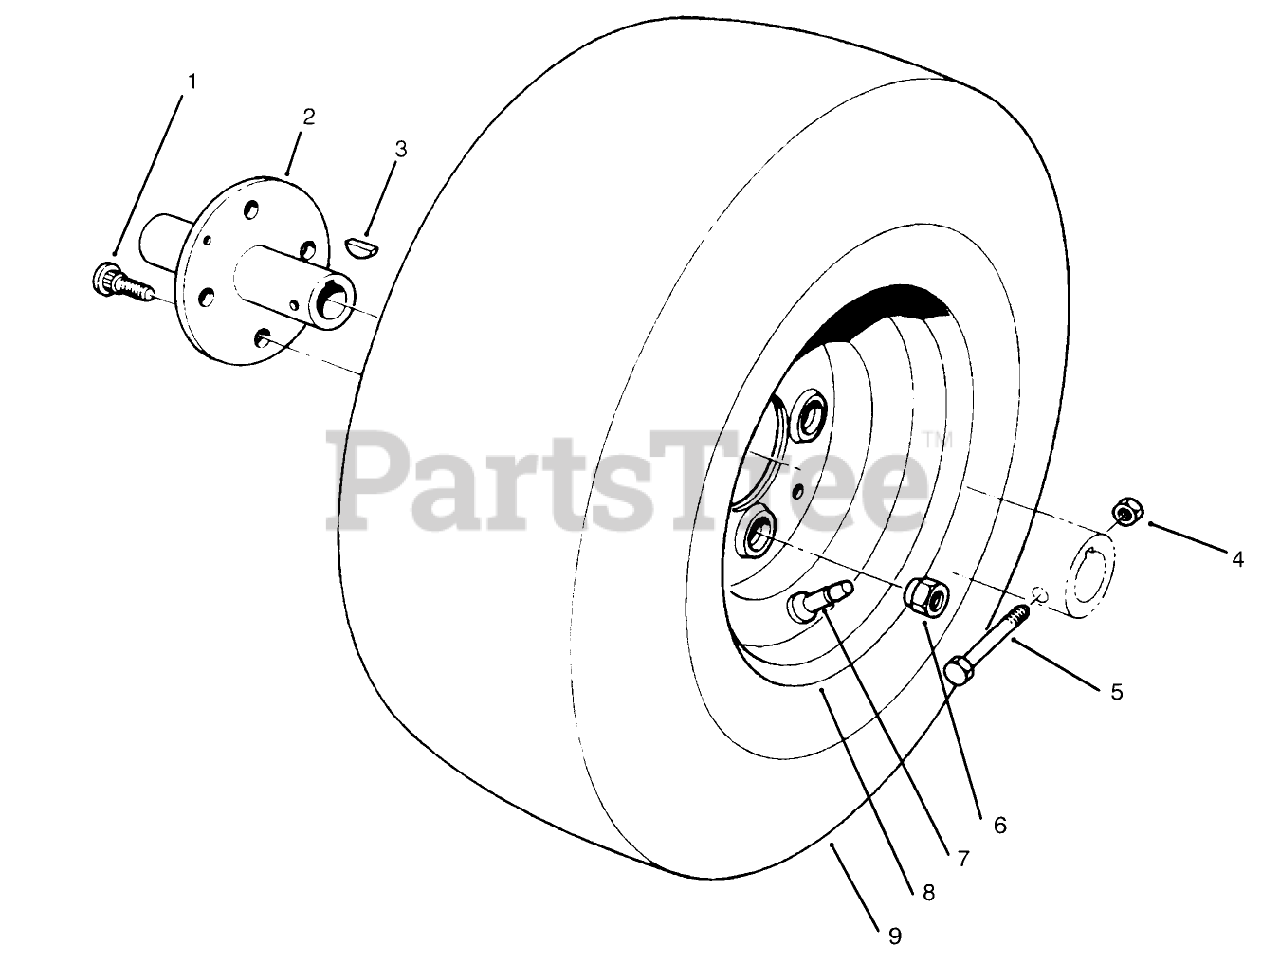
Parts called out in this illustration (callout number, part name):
1	1/2-20X1.25 BOLT
2	WHEEL HUB
3	KEY-WOODRUFF
4	NUT-LOCK, NI
5	SCREW-HH
6	NUT-LUG
7	STEM-VALVE
9	TIRE-4-Ply
